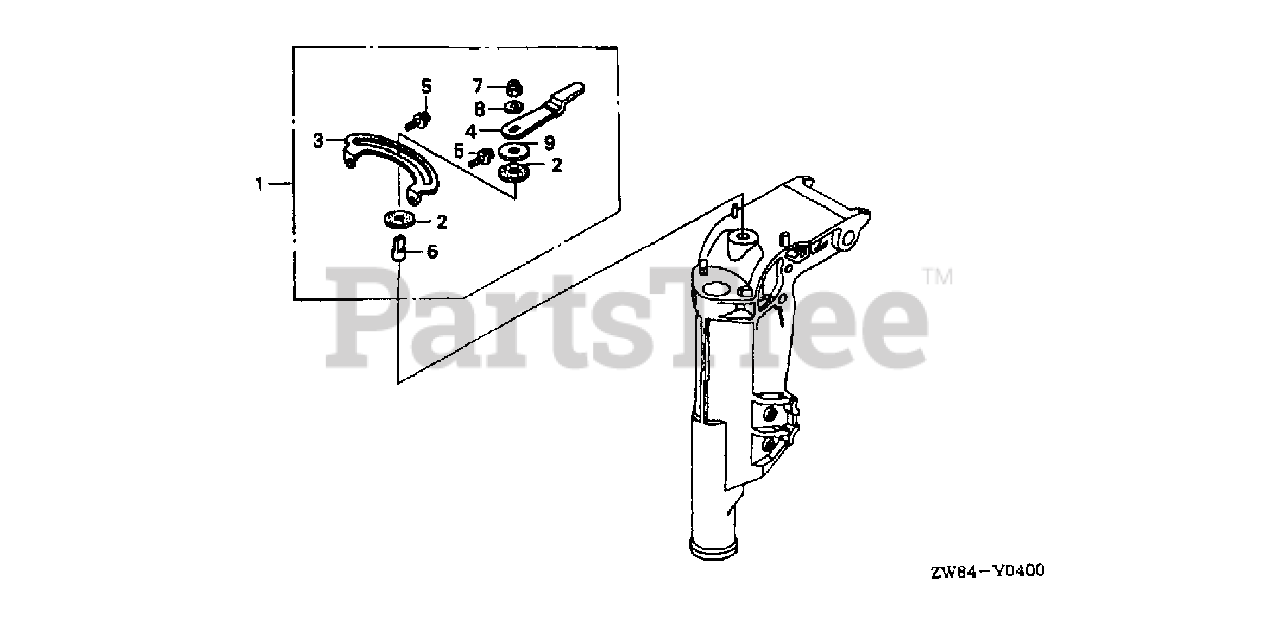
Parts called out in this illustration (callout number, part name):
1	FRICTION KIT, STEERING
2	BLOCK, FRICTION
3	PLATE, FRICTION
4	LEVER, FRICTION
5	BOLT, FLANGE (6X12)
6	BOLT, STUD (8X26)
7	NUT, SELF-LOCK (8MM)
8	WASHER (8MM)
9	WASHER, NYLON (8MM)
